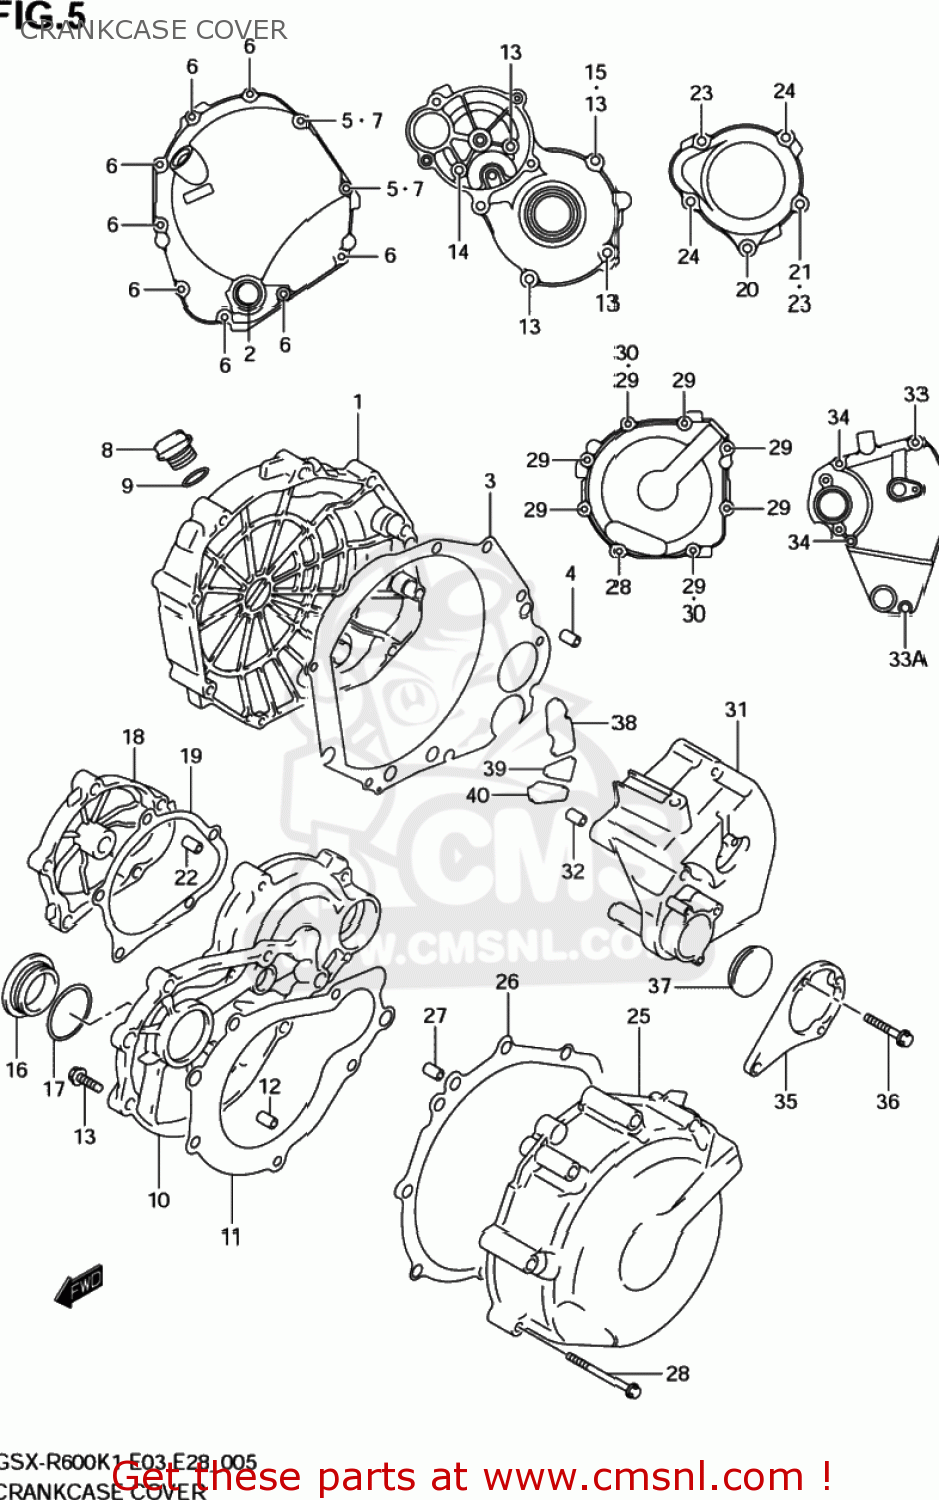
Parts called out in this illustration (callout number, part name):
1	COVER,CLUTCH
2	LENS,OIL LEVEL CHECK
3	GASKET,CL COVE (NAS)
4	PIN
5	GASKET(5.8X13X1.2) (NAS)
6	BOLT
7	BOLT
8	PLUG,OIL FILLER
9	O RING(D:3.1,ID:16.8)
10	COVER,STARTER CLUTCH
11	GASKET,STARTER CLUTCH COVER
12	PIN
13	BOLT,OIL PAN
14	BOLT
15	GASKET(5.8X13X1.2) (NAS)
16	PLUG
17	O RING(D:3.1,ID:32.7)
18	CAP,STARTER IDLE GEAR
19	GASKET,START IDLE GEAR CAP (NAS)
20	BOLT
21	GASKET(5.8X13X1.2) (NAS)
22	PIN
23	BOLT,OIL PAN
24	BOLT
25	COVER,MAGNETO
26	GASKET,MAGNETO COVER (NAS)
27	PIN
28	BOLT
30	GASKET(5.8X13X1.2) (NAS)
31	COVER,ENGINE SPROCKET
32	PIN
33	BOLT
33A	BOLT
34	BOLT
35	BRACKET,SPROCKET COVER
36	BOLT,OIL FILLE
37	CAP(OD:36)
38	DAMPER,SPROCKET COVER NO.1
39	DAMPER,SPROCKET COVER NO.2
40	DAMPER,SPROCKET COVER NO.3
